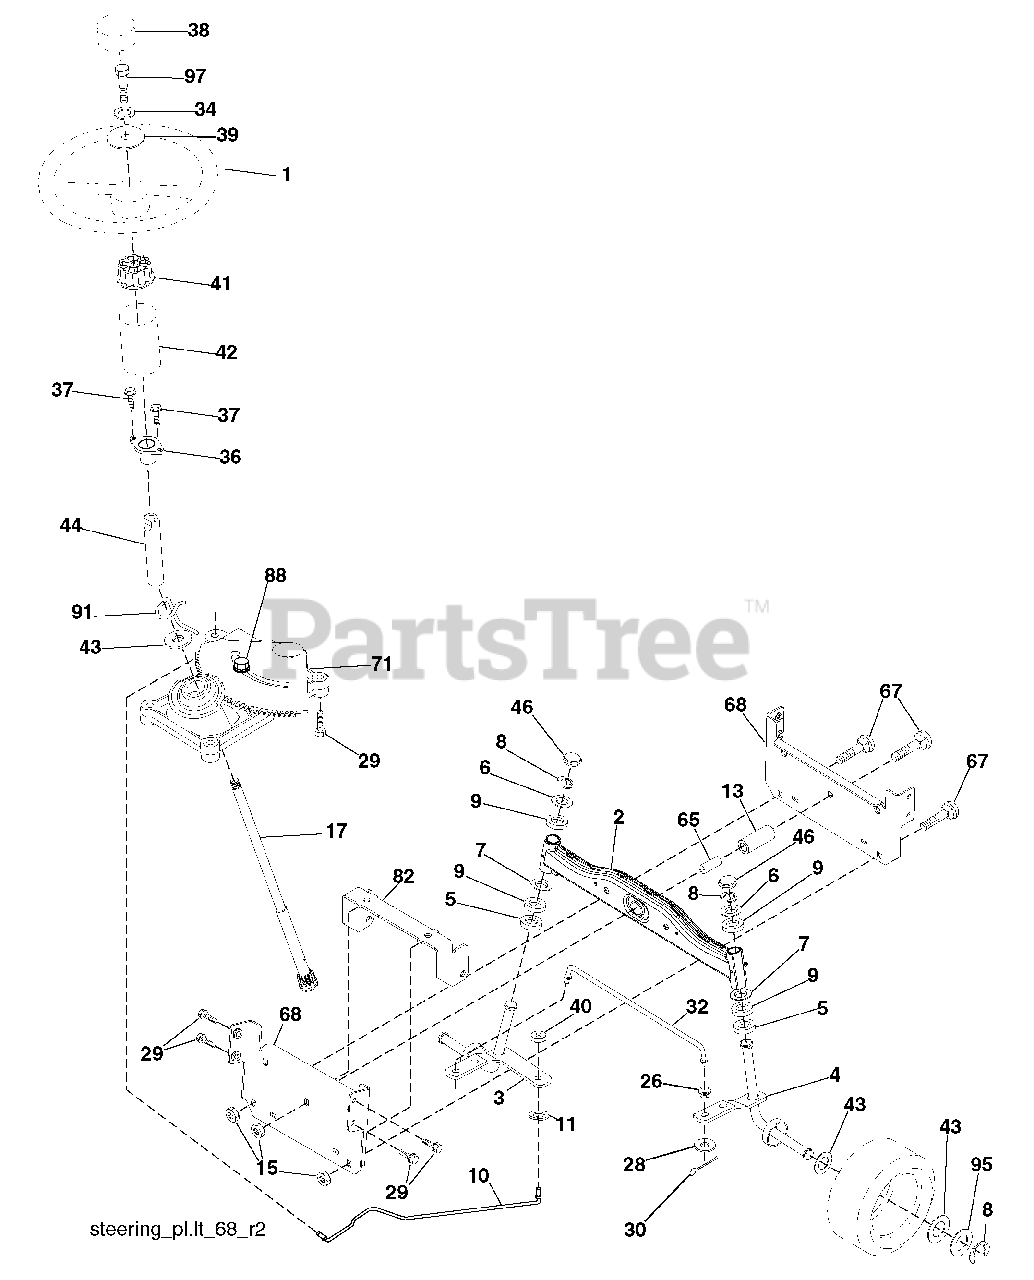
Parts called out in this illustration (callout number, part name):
1	Wheel Steering
2	Axle Asm
3	Spindle Asm LH
4	Spindle Asm RH
5	Bearing Race Thrust Harden
6	Washer 25/32 x 1-5/8 x 16 Ga.
7	Washer 27/32 x 1-1/4 x 16 Ga.
8	Ring Klip #t5304-75
9	Bearing Col Strg Blk
10	Link Drag
11	Washer Lock Hvy Hlcl Spr 3/8
13	Spacer earing Axle Front
15	Hexflange Lock
17	Shaft Asm Strg
26	Bushing Link Drag Blk LR
28	Washer 13/32 x 7/8 x 16 Ga.
29	Screw 3/8-16 x 3/4
30	Pin Cotter 1/8 x 3/4 Cad
32	Rod Tie Wire Form 19 75 Mech
34	Washer Lock Hvy Hlcl Spr 5/16
36	Bushing Strg 5/8 Id Dash
37	Screw
38	Cap Wheel Steer Ayp
39	Washer 11/32 ID x 2-3/8 OD x 12 Ga.
40	Nut Crownlock 3/8-24
41	Adaptor Wheel Strg
42	Boot Dash Mtl Steering Blk
43	Washer 25/32 x 1 1/4 x 16 Ga.
44	Extension Steering
46	Cap Spindle Fr Top Blk
65	Spacer Brace Axle
67	Bolt RDHD SQNK 3/8-16 x 2-1/4
68	Brace Axle
71	Steering Asm.
82	Bracket Susp Chassis Front
88	Bolt Shoulder 7/16-20
91	Clip Steering
95	Washer Harden .793 x 1.637 x 060
97	Bolt 5/16-18 unc x 4"L Hlcl Spr. 5/16
